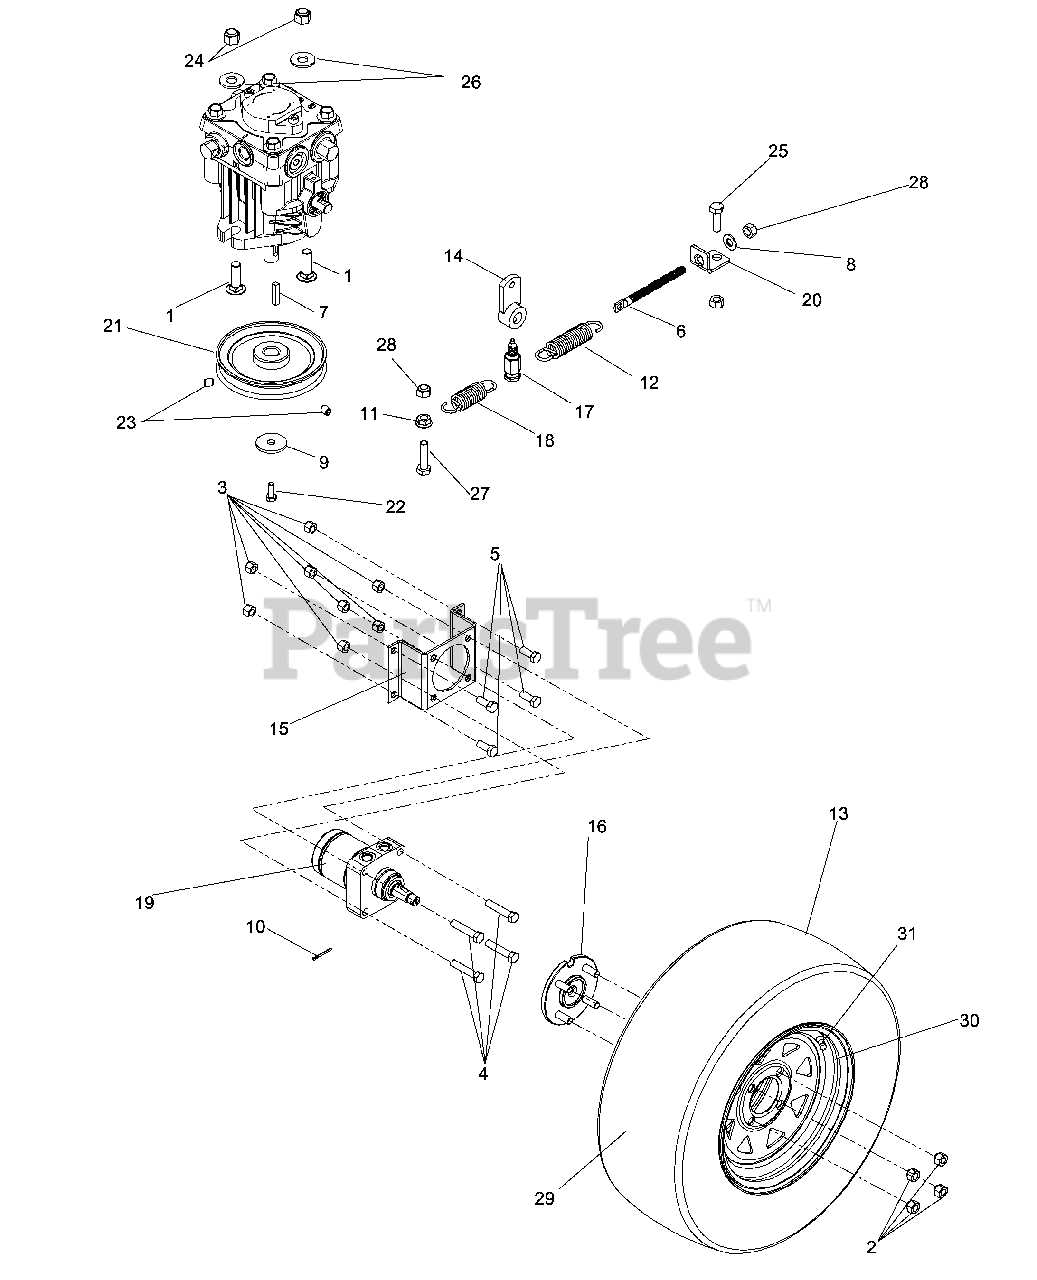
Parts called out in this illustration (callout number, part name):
1	RHSNB 3/8-16 X 1-1/4
2	LUG NUT 1/2F
3	NUT 1/2-13 HEX NYLOC ZD
4	HEX SCREW 1/2-13 X 2.5" GR 5
5	HCS 1/2-13 X 1-1/4
6	BRAKE ROD
7	KEY-3/16 DIA X 1
8	5/16STD FL WASH TYPA
9	5/16ID X 1/8THK WASHER
10	1/8DIAX1-1/2 COT PIN
11	5/16-18 FLANGED L-NUT
12	SPRING - 3.50
13	TIRE ASM 23X8.5-12
14	CONTROL ARM DRILLED
15	MT. MOTOR
16	HUB.WHEEL.ZTR
17	SET SCREW
19	WHEEL MOTOR
20	SPRING BRKT.
22	CAPSCREW HH 6MM X 16MM
23	SET SCREW 5/16 NYLOC
24	NUT 3/8-16 NYLOC
25	HCS 5/16C X 1
26	WASHER 3/8 FLAT
27	HCS 5/16C X 1 1/4
28	NUT 5/16 NYLOC
29	TIRE-REAR 23X8.5-12
30	RIM 12 X 7
